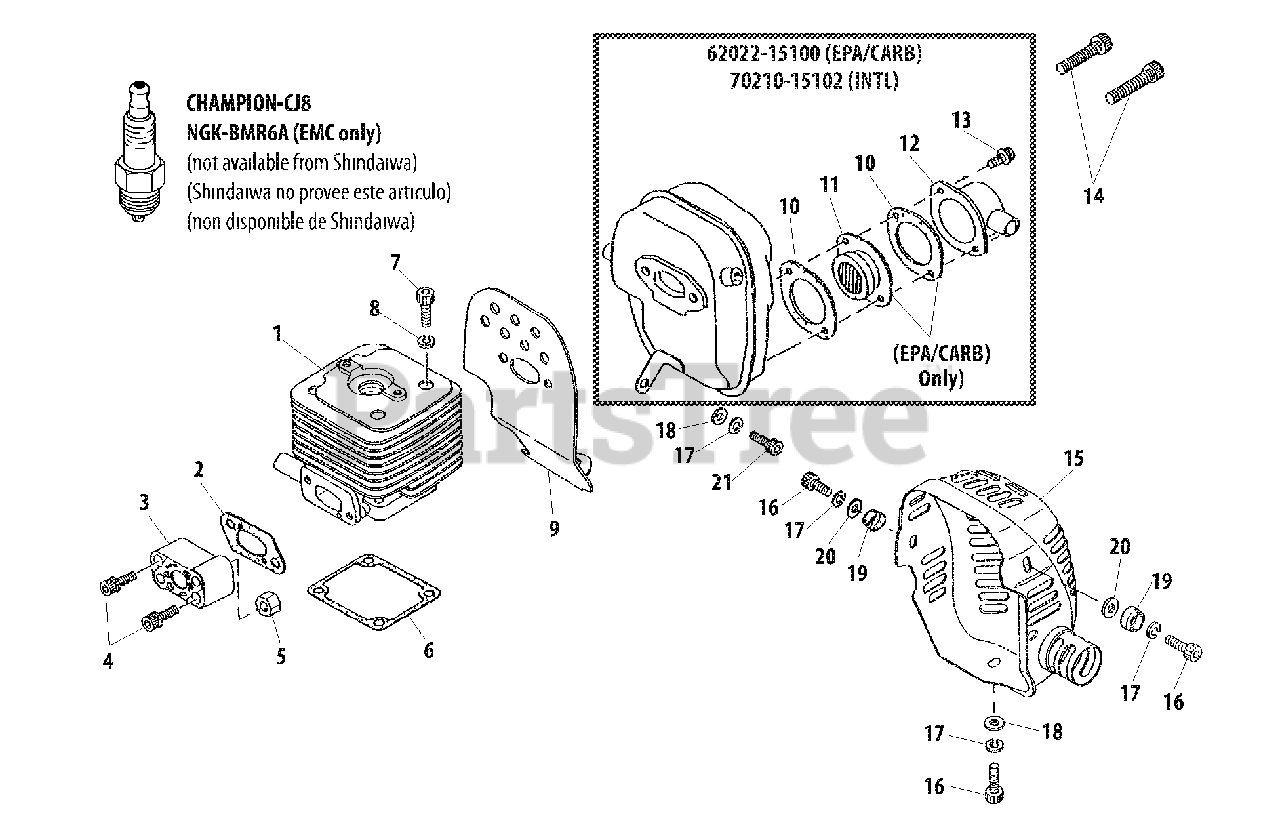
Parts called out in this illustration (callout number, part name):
1	CYLINDER
2	GASKET, INTAKE
3	INSULATOR
4	BOLT M5×25
5	NUT
6	GASKET, CYLINDER
7	BOLT 5×25
8	WASHER, SPRING 5
9	GASKET, EXHAUST
10	GASKET, EXHAUST
11	SCREEN, SPARK ARRESTER
12	DEFLECTOR, EXHAUST
13	SCREW M4×8
14	BOLT 6×25
15	COVER, MUFFLER
16	BOLT 5×10
17	WASHER, SPRING 5
18	WASHER 5 MM
19	COVER
20	WASHER
21	BOLT 5
62022-15100	MUFFLER
70210-15102	MUFFLER
